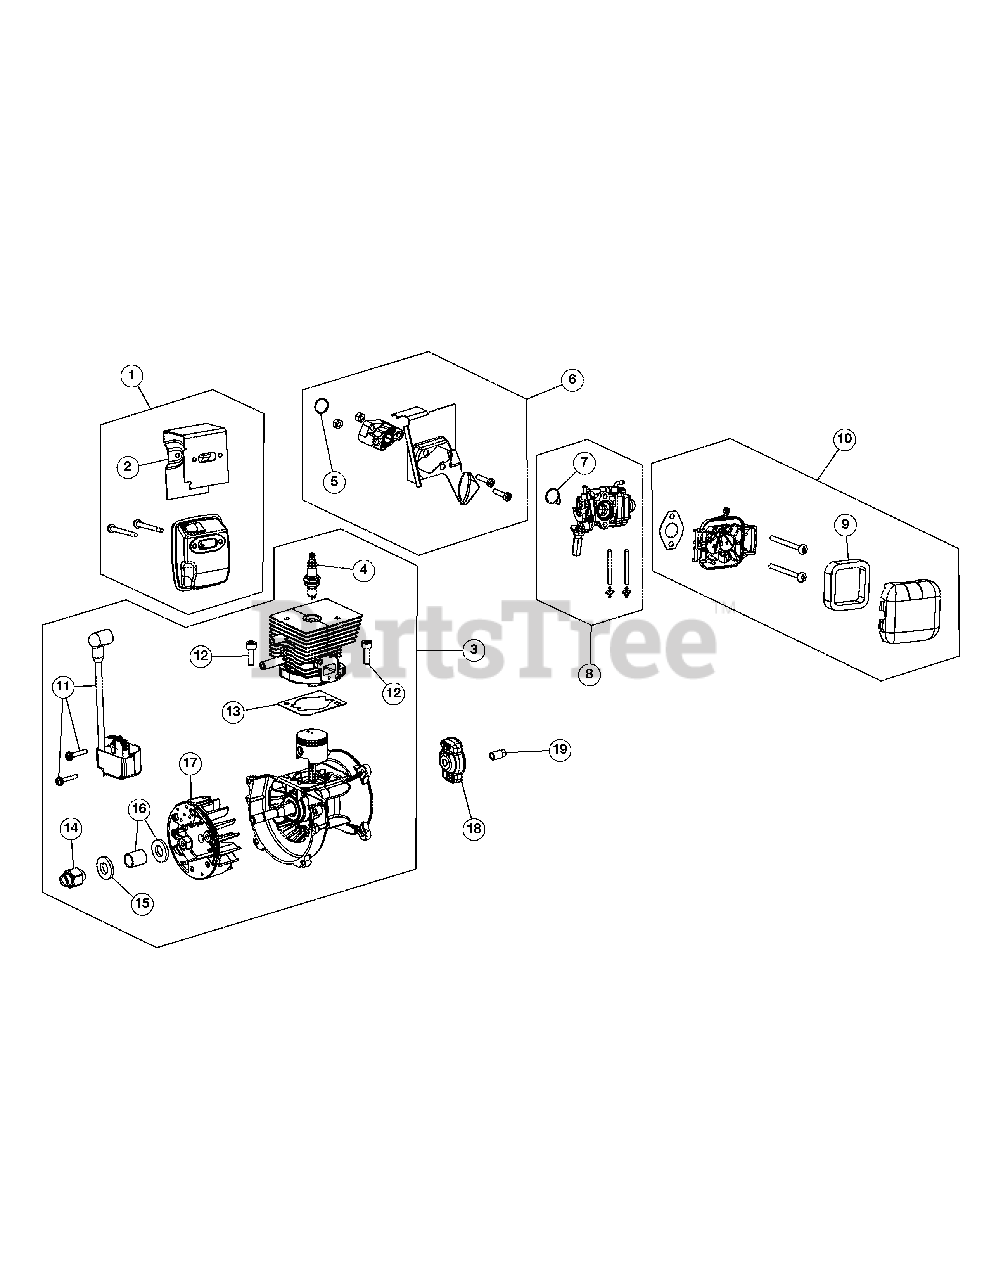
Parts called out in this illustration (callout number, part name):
1	Muffler Assembly (Incl. 2)
2	Muffler Gasket
3	Shortblock Assembly (Incl. 4 & 11-17)
4	Spark Plug
5	Insulator O-Ring
6	Insulator Assembly (Incl. 5)
7	Carburetor Gasket
8	Carburetor Assembly (Incl. 7)
9	Air Filter
10	Aircleaner Assembly (Incl. 9)
11	Module Assembly
13	Cylinder Gasket
14	Flywheel Adapter
15	Washer
16	Bushing
17	Flywheel Assembly
18	Pawl Assembly
19	Electric Start Adapter
